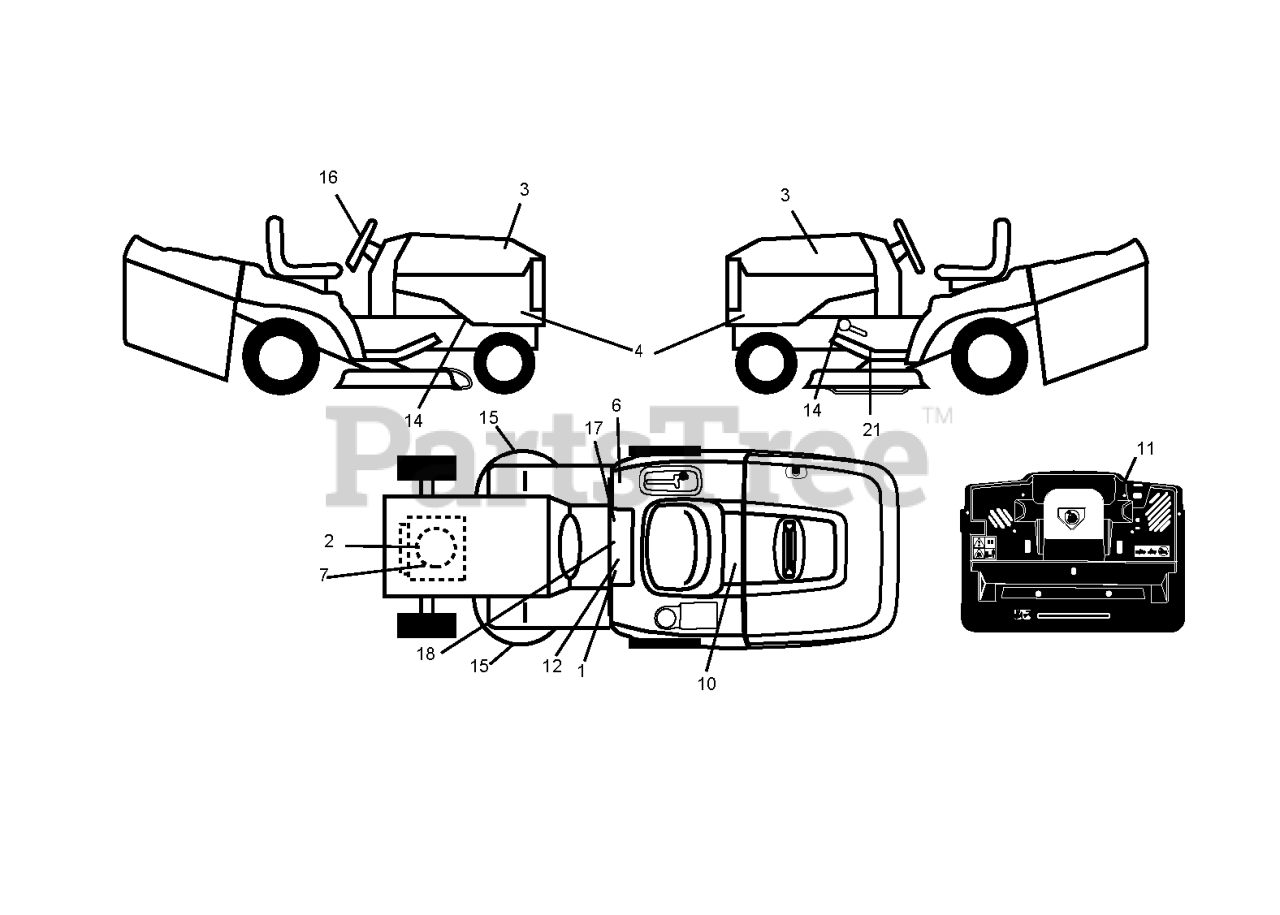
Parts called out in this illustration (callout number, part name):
1	LABEL
3	DECAL.HOOD.NAMELOGO.HUSQ
6	Decal, Fender 100 DB/CE
7	DECAL
10	DECAL BTRY SYMBOLS
11	DECAL.INTERNATIONL.CUTFINGER
12	DECAL
16	DECAL.WHEEL.STRG.LGN.H
17	DECAL PARK BRAKE
